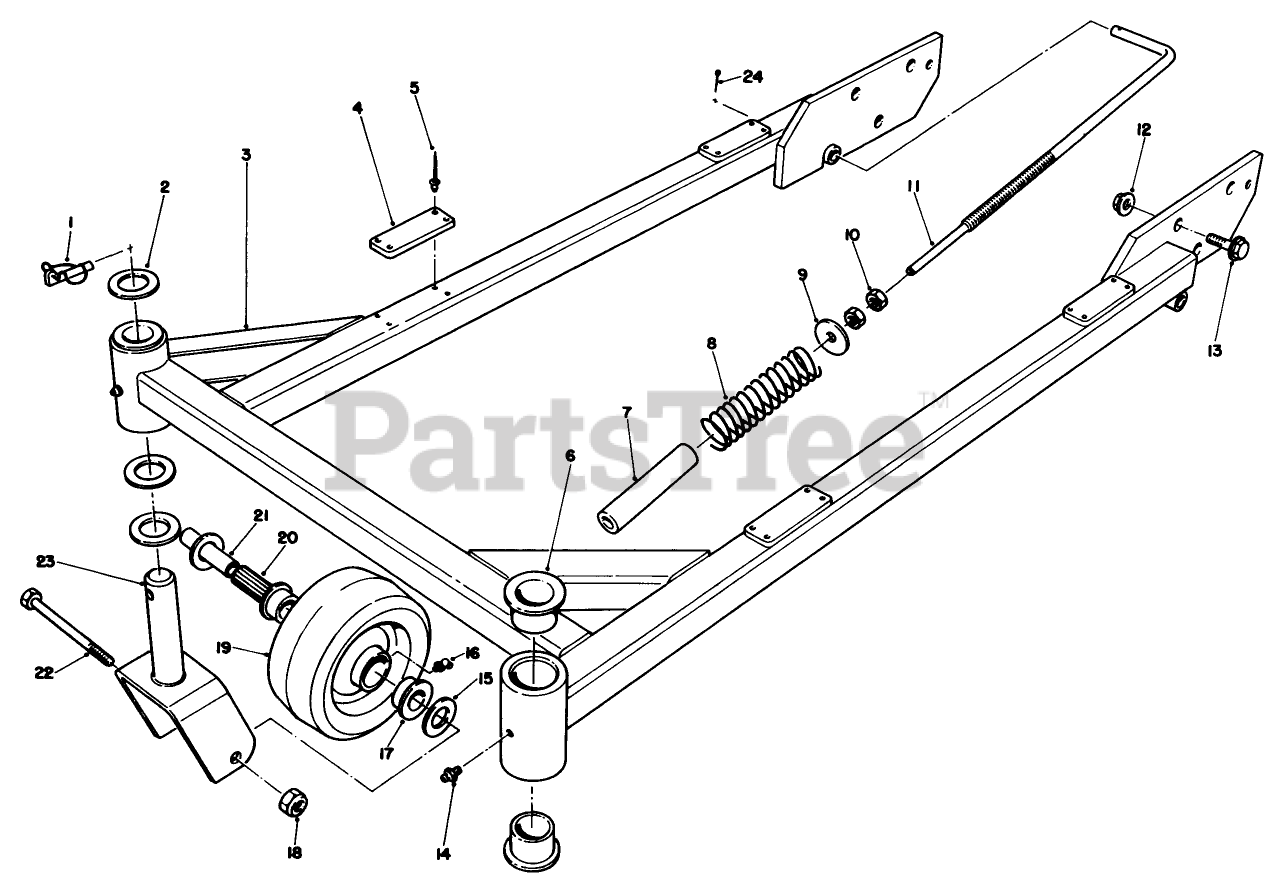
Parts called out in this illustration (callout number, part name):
1	PIN-LYNCH
2	WASHER-THRUST
3	CARRIER FRAME WA
4	Pad-Rubber
5	RIVET
6	Bushing
7	SLEEVE-TUBE, 36 INCH
8	SPRING-COMPRESSION
9	WASHER
10	NUT-JAM
11	ADJUSTING SHAFT
12	NUT-LOCK, FLANGE
13	SCREW-HHF
14	FITTING-GREASE
15	SPACER-WHEEL
16	FITTING-LUBE, 45 DEG
17	BEARING-OUTSIDE
18	NUT-HEX
19	Wheel-Castor (Incl. Ref. #16, 17 & 20)
20	BEARING-ROLLER
21	SPANNER
22	SCREW-HH
23	Fork-Caster
24	PIN-COTTER
